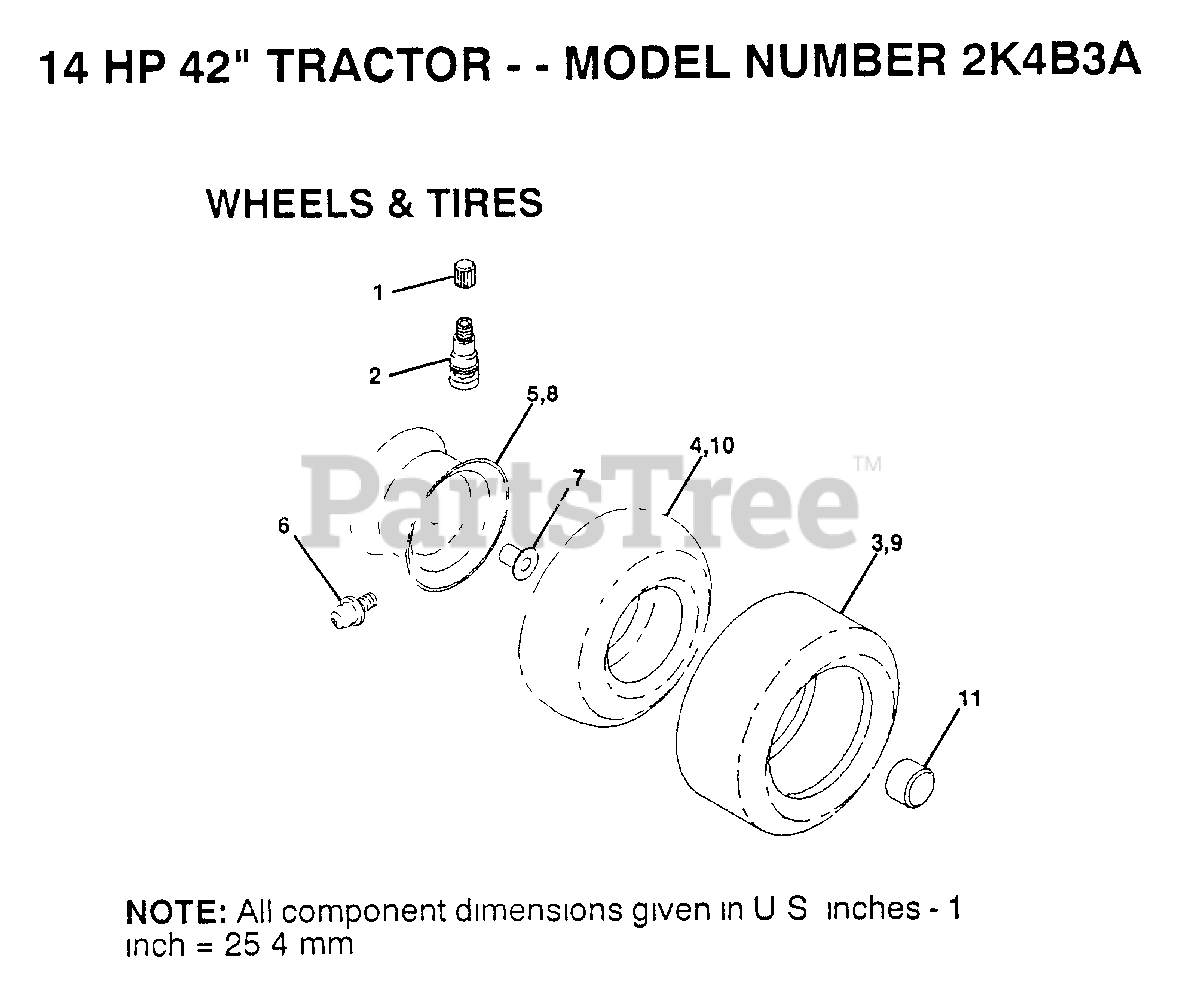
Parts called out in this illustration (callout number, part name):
1	VALVE CAP
2	VALVE STEM LT
4	TUBE.5.3/4.5/6
6	FITTING LT
7	"FLANGE, BEARING"
10	TUBE.18X9.5-8
11	HUB CAP
